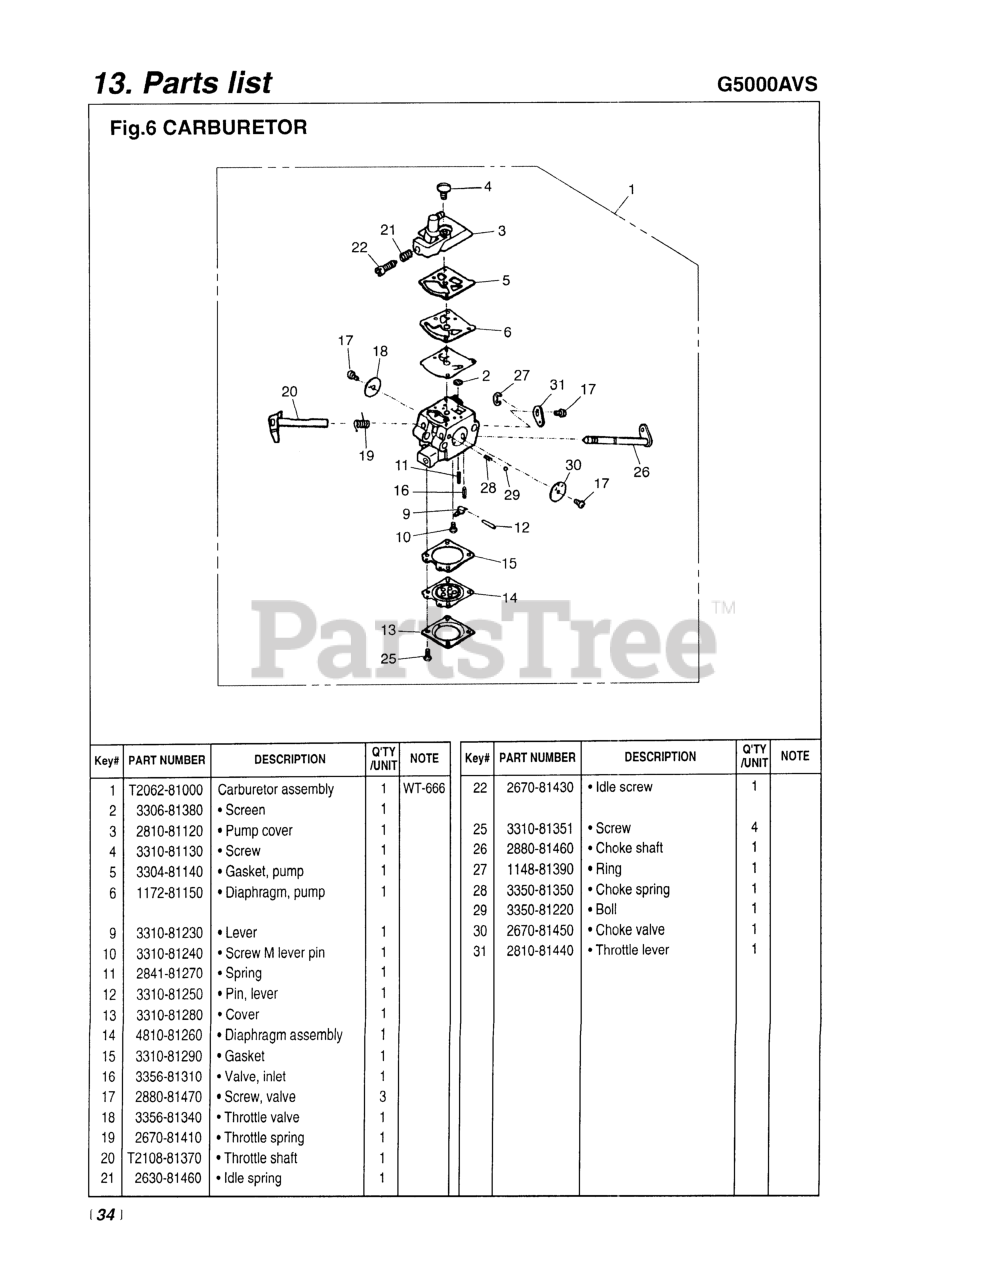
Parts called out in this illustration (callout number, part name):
1	CARBURETOR ASSEMBLY (WT-666-1)
3	COVER ASSEMBLY
5	GASKET, PUMP
6	DIAPHRAGM, PUMP
9	LEVER
11	SPRING (USE 2867-81270)
12	PIN, METERING LEVER
14	DIAPHRAGM (RPLS 3310-81260)
16	VALVE, INLET
17	SCREW (RPLS 3310-81360)
18	VALVE, THROTTLE
19	SPRING, RETURN
20	SHAFT ASSEMBLY, THROTTLE
21	SPRING, IDLE
25	SCREW ASSEMBLY
26	SHAFT, CHOKE
28	SPRING
29	BALL, FRICTION
30	VALVE, CHOKE
